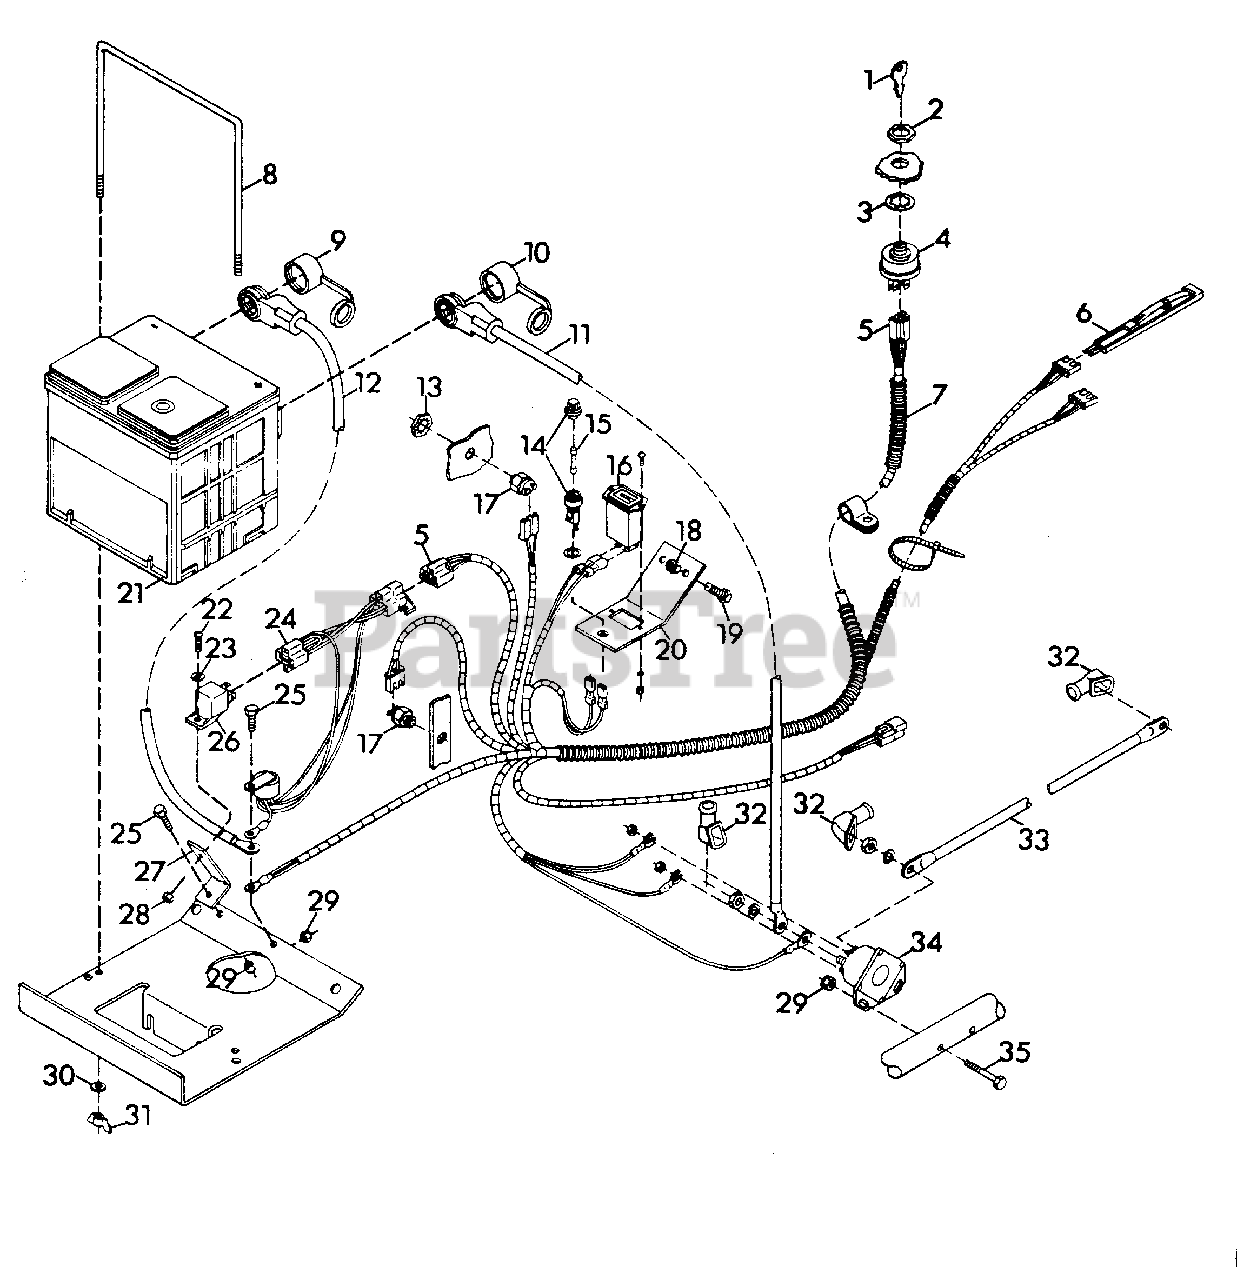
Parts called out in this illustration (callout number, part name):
1	KEY, IGNITION
2	NUT, JAM 9/16-24
3	WASHER, LOCK
4	SWITCH, IGNITION
5	CONNECTOR
6	SWITCH, SEAT
7	HARNESS, WIRING PRO MASTER-50
8	ROD, BATTERY
9	COVER, BATTERY NEG.
10	COVER, BATTERY POS.
11	CABLE, ELECTRICAL
12	CABLE, ELECTRICAL
13	NUT, STAMPED 9/16-18
14	FUSE, PANEL
15	FUSE, 25 AMP
16	HOURMETER
17	SWITCH, INTERLOCK
18	NUT, LOCK 3/8-16
19	BOLT, HEX 3/8-16X.875
20	BRACKET
21	BATTERY, DELCO MAINTENANCE-FREE #101 -REPLACEMENT BATTERY #83-50
22	SCREW, MACH. 10-24X.75 PHD
23	WASHER, FLAT .188X.438X.049
24	MODULE, TIME DELAY
25	BOLT, HEX 1/4-20X1.00
26	RELAY
27	BRACKET, FUEL LINE SUPPORT
28	NUT, LOCK 10-24
29	NUT, LOCK 1/4-20
30	WASHER, FLAT .281X.625X.065
31	NUT, WING 1/4-20
32	BOOT, BATTERY CABLE
33	CABLE
34	SWITCH, MAGNETIC
35	BOLT, HEX 1/4-20X2.00
